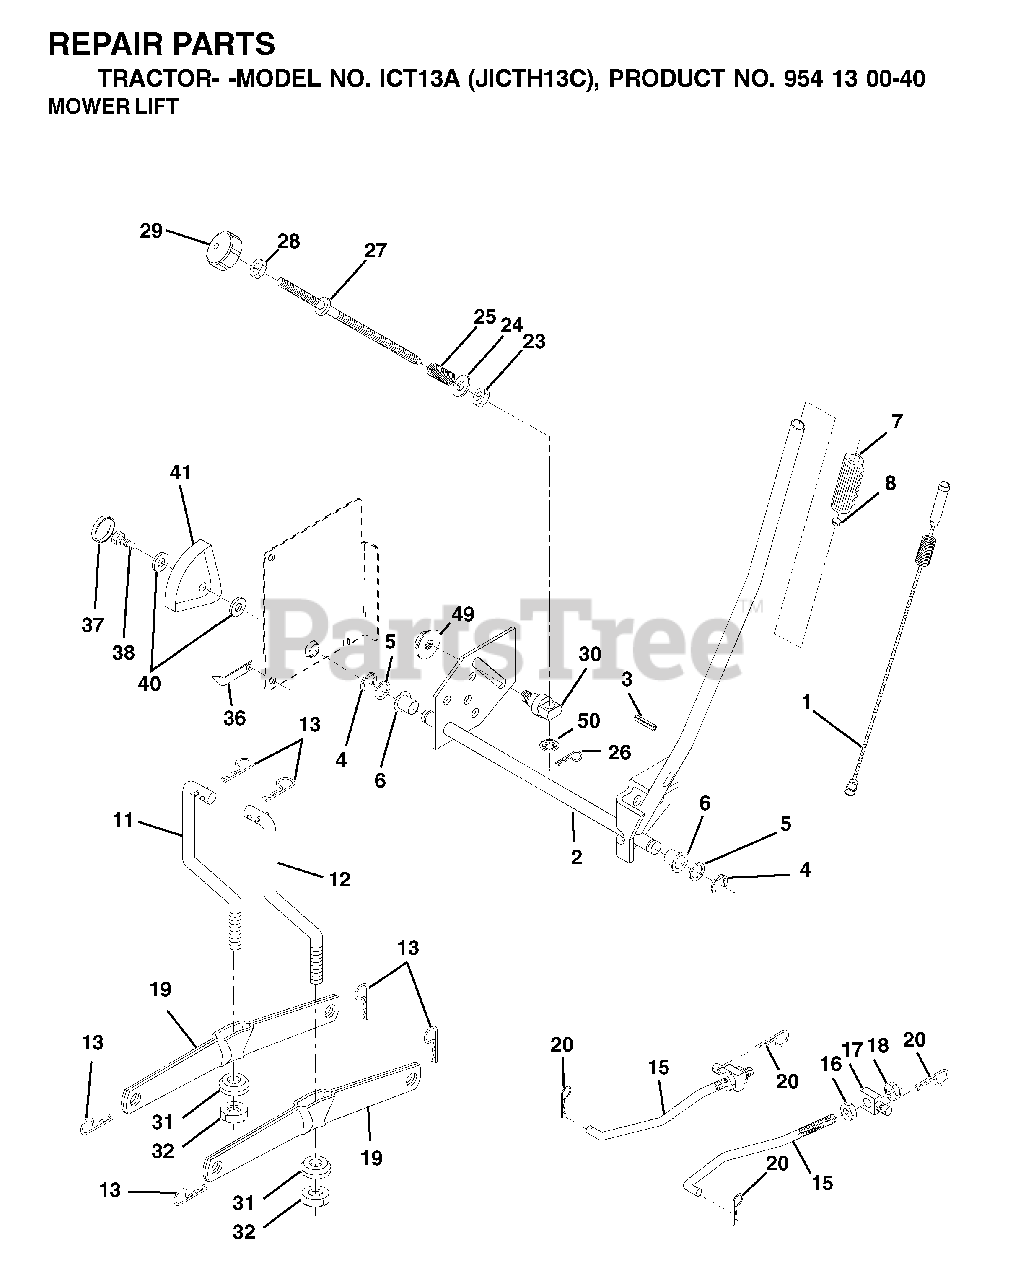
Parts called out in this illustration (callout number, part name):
1	WIRE ASM INNER W/ PLUNGER LT
2	SHAFT ASM R HANDLE
3	PIN GROOVE
4	RETAINING RING LT
6	BEARING.NYLON
7	GRIP HANDLE
8	PLUNGER BUT KIT
11	LINK
12	LINK
13	RETAINER-SPRNG RB
15	LINK.SUSPENSION.FRONT
16	NUT
17	TRUNION
18	NUT
19	ARM.REAR.SUSPENSION
20	SPRING RETAINER
25	SPRING**
26	RETAINER CLIP
27	ROD ADJ LIFT
28	NUT
29	KNOB INF 3/8-16
31	BEARING.PIVOT.LIFT
32	NUT CROWNLOCK 3/8-24
36	POINTER, HEIGHT INDICATOR
37	PLUG,HOLE
38	SCREW 5/16-18X1
41	HEIGHT INDICATOR
49	NUT
50	NUT PUSH M
